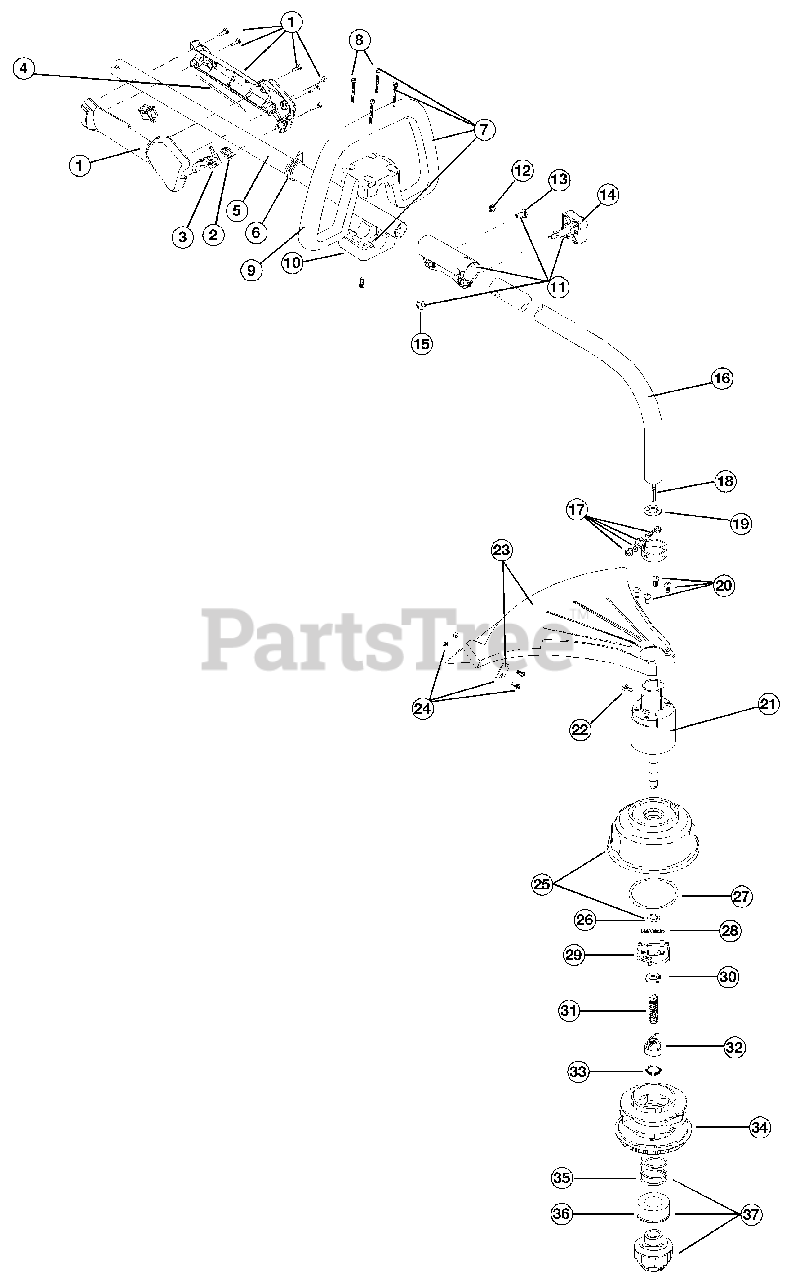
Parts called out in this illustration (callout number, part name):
1	Throttle Housing Assembly
2	Throttle Trigger Spring
3	Throttle Trigger
4	Throttle Cable Assembly
5	Upper Drive Shaft Housing Assembly
6	Harness Clip
7	Deluxe D-Handle Assembly
9	Deluxe D-Handle
10	Bottom Clamp
11	EZ-Link Coupler
14	Adjustment Knob
15	Knob Retaining Nut
16	Lower Drive Shaft Housing Assembly
17	Lower Clamp Assembly
18	Lower Flexible Drive Shaft
19	Palnut
20	Shield Mounting Screw
21	Bushing Housing Assembly
22	Anti-Rotation Screw
23	Shield and Blade Assembly
24	Blade Assembly
25	Outer Spool & Eyelet Assembly
27	Thrust Washer
28	Small Spring
29	Slider
34	Inner Reel
35	Large Spring
37	Bump Head Knob Assembly
